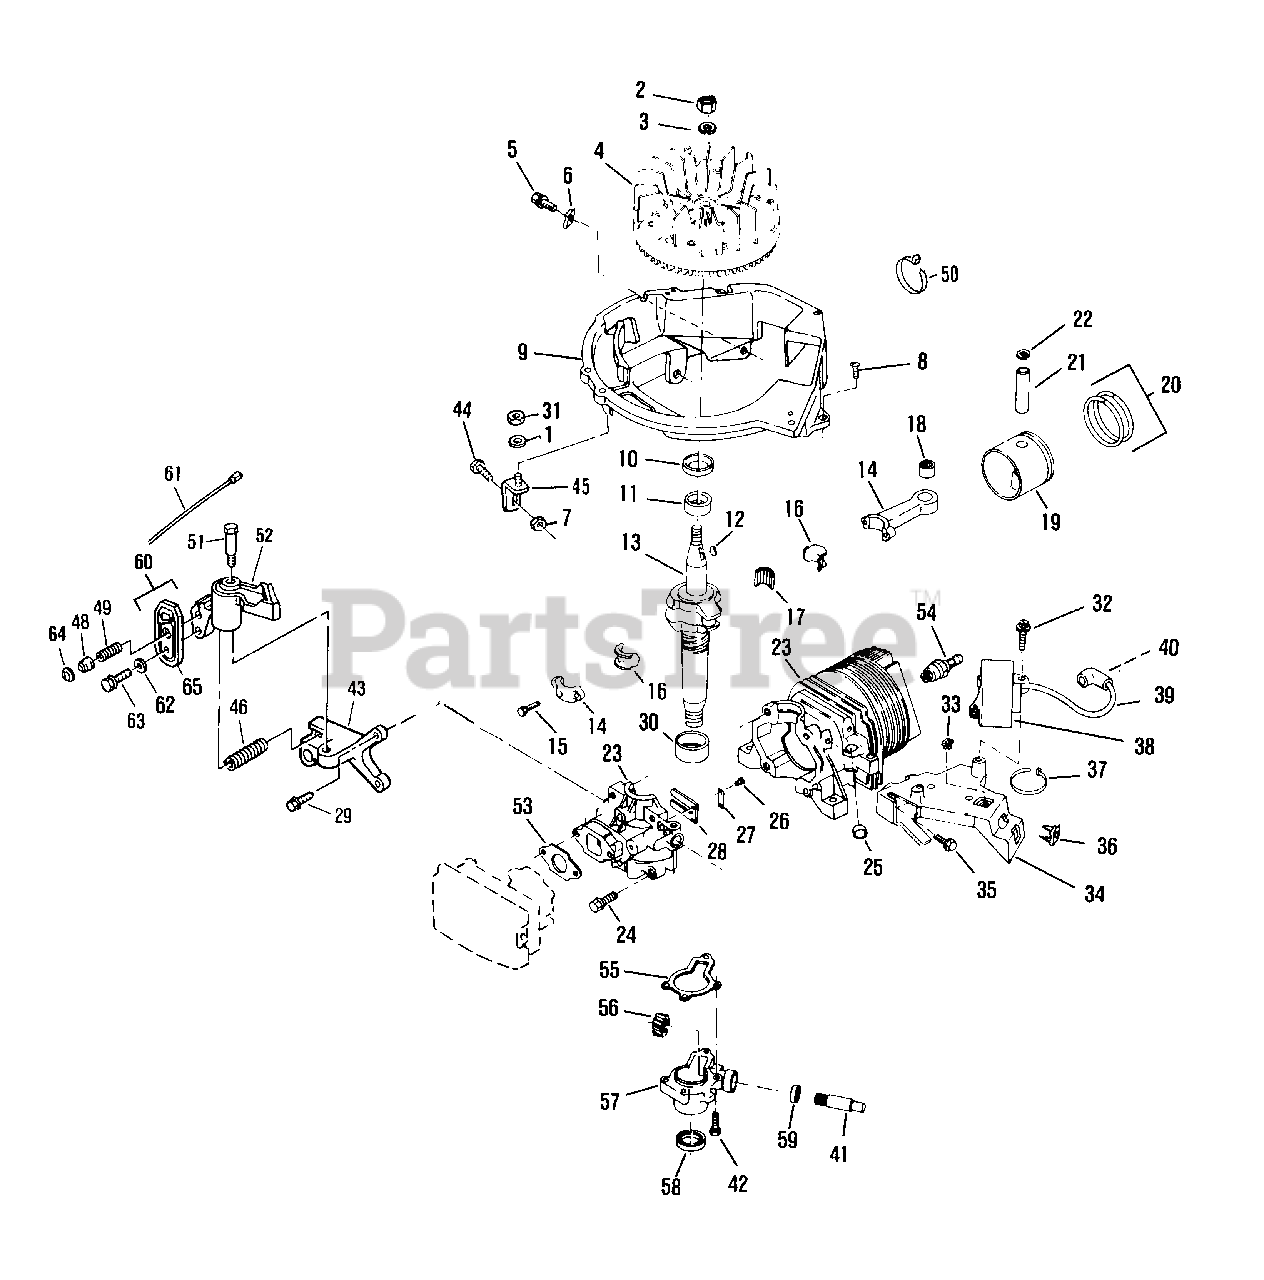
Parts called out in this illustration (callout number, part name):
1	Washer
2	Nut-Flywheel
3	Lockwasher
4	Flywheel
5	Screw
6	"J" Clip
7	Nut
8	Screw-Shroud Base to C.D. Bracket
9	Base-Shroud
10	Oil Seal-Upper
11	Bearing-Upper
12	Key-Flywheel
13	Crankshaft
14	Connecting Rod Assembly
15	Screw-Cap
16	Liner Split
17	Needle Bearing Set
18	Bearing Assembly
19	Piston and Ring Set
20	Ring Set
21	Wrist Pin
22	Retaining Ring
23	Cylinder and Crankcase Cover Assembly
24	Screw-Cover to Crankcase
25	Plug
26	Screw-Reed to Crankcase Cover
27	Plate-Reed Hold Down
28	Reed
29	Screw-Brake Mounting Bracket
30	Bearing-Lower
31	Nut
32	Screw-C.D. Mounting
33	Grommet-C.D. Bracket
34	Bracket-Ignition Mounting
35	Screw
36	Grommet-C.D. Bracket
37	Tie Strap
38	C.D. Ignition Module and Lead Assembly
39	High Tension Lead and Cover Assembly
40	Spring Terminal
41	Driveshaft
42	Screw-Gear Box
43	Bracket-Brake
44	Bolt
45	Tie Strap
46	Spring-Brake
48	Actuator-Brake Lever
49	Spring-Cable Retainer
50	Tie Strap
51	Bolt-Shoulder
52	Brake Assembly
53	Gasket-Carburetor to Crankcase Cover
54	Spark Plug
55	Gasket-Gear Box
56	Gear
57	Gear Box Assembly
58	Oil Seal Crankshaft
59	Seal-Driveshaft
60	Switch Assembly
61	Lead Assembly
62	Washer
63	Bolt
64	Retainer
65	Case Assembly-Only
